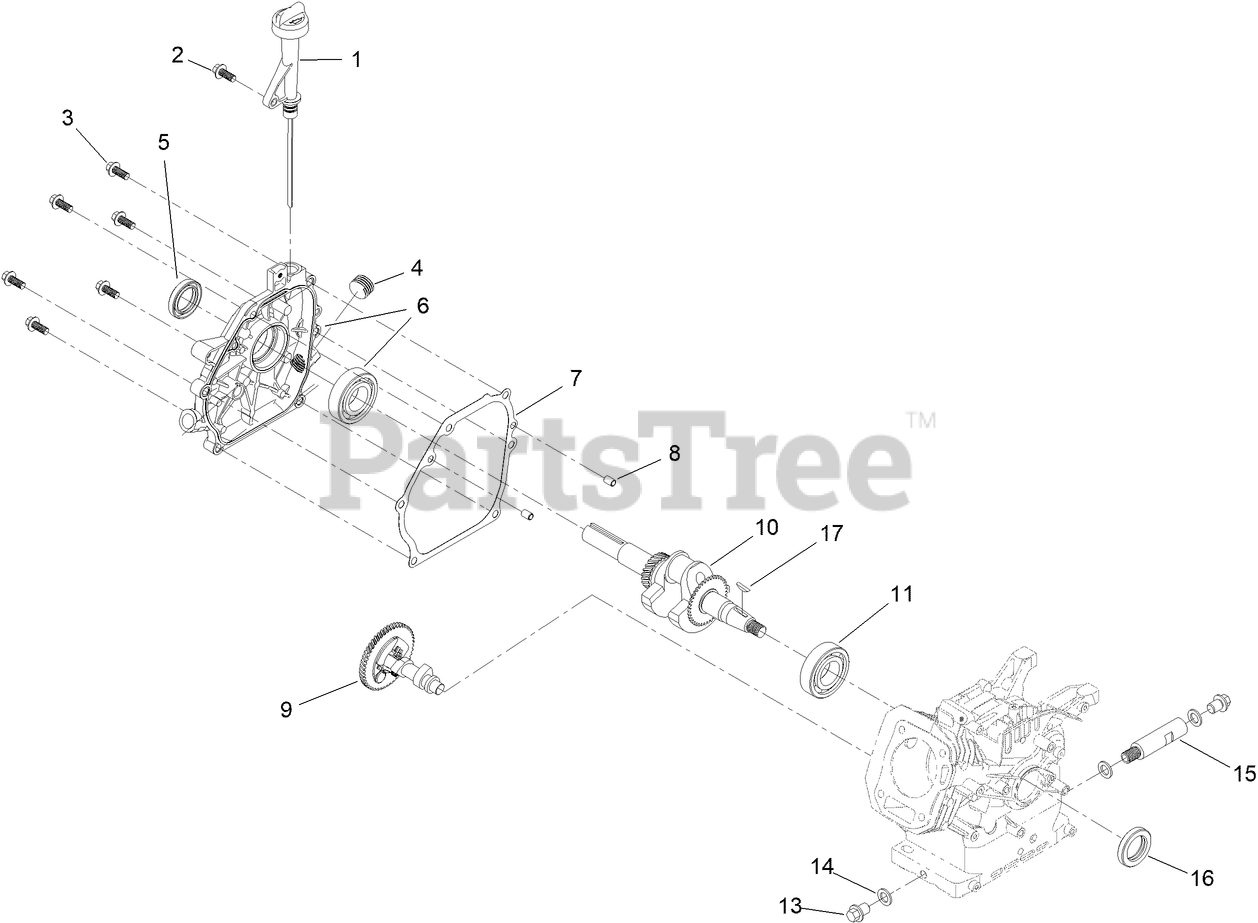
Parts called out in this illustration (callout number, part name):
1	OIL FILL ASM
2	SCREW-HHF
3	SCREW-HHF
4	PLUG-DRAIN
5	SEAL-OIL
6	CRANKCASE COVER ASM
7	GASKET-COVER, CRANKCASE
8	PIN-DOWEL
9	CAMSHAFT
10	CRANKSHAFT
11	BEARING-BALL
13	SCREW-HHF
14	WASHER-PLAIN
15	TUBE-DRAIN, OIL
16	SEAL-OIL
17	KEY-WOODRUFF
